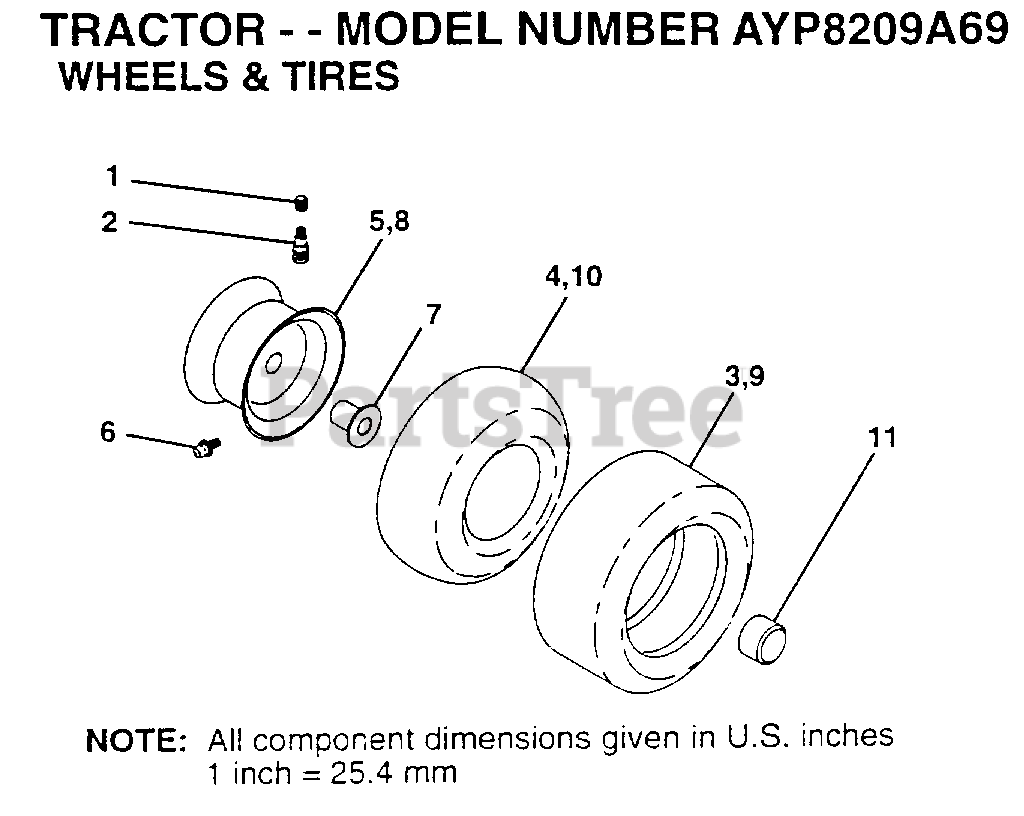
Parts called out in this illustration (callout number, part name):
1	VALVE CAP
2	VALVE STEM LT
4	TUBE.16X6.5/7.5-8
5	"RIM ASM 8"" FRT"
6	ZERK FITTING M
7	"FLANGE, BEARING"
8	"RIM ASM 12"" REAR"
10	TUBE.23X8/10-12
11	HUB CAP
